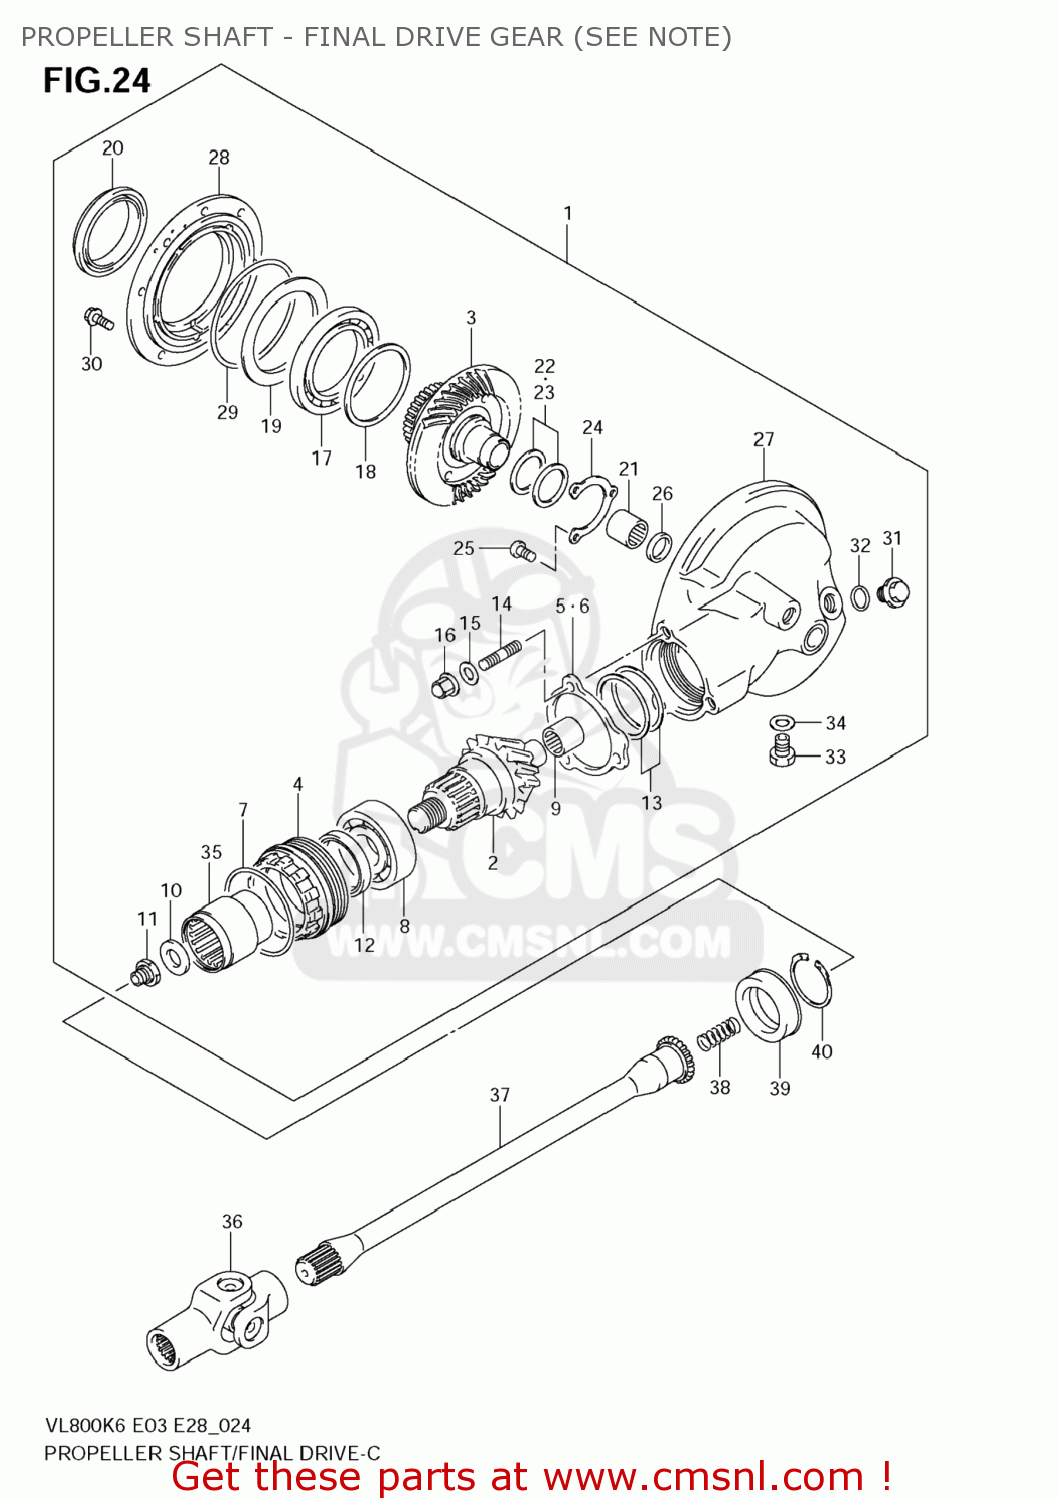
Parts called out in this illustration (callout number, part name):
1	GEAR&CASE SET,
2	GEAR,FINAL DRIVE BEVEL(NT:11)
3	GEAR,FINAL DRIVEN BEVEL(NT:34)
4	STOPPER,FINAL DRIVE BEARING
5	PLATE,BEARING STOPPER
6	PLATE,BEARING STOPPER
7	O RING(D:1.9,ID:61.6)
8	BEARING(30X62X23.8)
9	BEARING(17X32X16)
10	WASHER(16X29X4)
11	NUT
12	SEAL,OIL(38X54X6)
13	SHIM SET,FINAL DRIVE GEAR
14	BOLT,STUD
15	WASHER
16	NUT
17	BEARING(70X110X13)
18	SHIM SET,DRIVEN GEAR BEARING
19	PLATE,FINAL DRIVEN BRG OIL
20	SEAL,OIL(70X96X16)
21	BEARING(32X46X17.7)
22	SHIM SET,FINAL DRIVEN GEAR
23	SHIM SET,FINAL DRIVE GEAR
24	RETAINER,FINAL DRIVEN GEAR BRG
25	SCREW
26	SEAL,OIL(30X42X7)
27	CASE,FINAL
28	CASE,FINAL GEAR BEARING
29	O RING(D:3.5,ID:131.6)
30	BOLT
31	PLUG
32	O RING(D:2.4,ID:17.8)
33	PLUG(MAGNETO)
34	GASKET(13.8X18.8X4.8) (NAS)
35	COUPLING,FINAL DRIVE GEAR
36	YOKE COMP,UNIVERSAL JOINT
37	SHAFT,PROPELLER
38	SPRING
39	SEAL,OIL(28.4X48X15)
40	CIRCLIP
